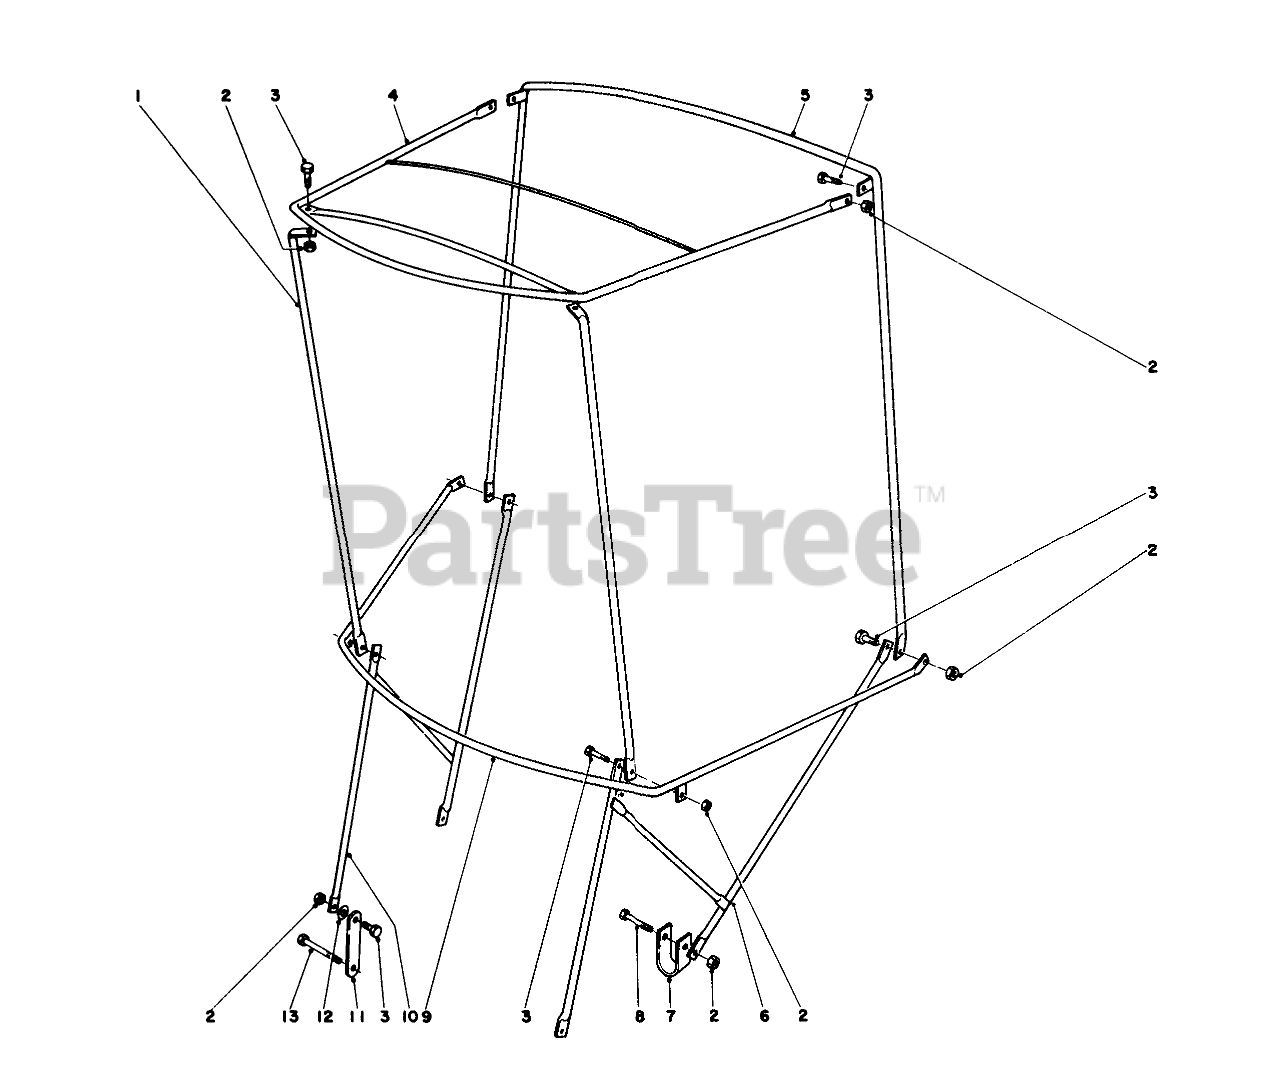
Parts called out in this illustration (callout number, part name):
2	NUT-LOCK
3	SCREW-HH
4	FRAME-TOP
5	BOW-VERTICAL, REAR
6	Attaching Bracket, L.H.
7	U CLAMP
8	SCREW-HH
9	BOW-CURVED
10	Attaching Bracket, R.H.
11	Mounting Strap
12	WASHER-LOCK/EXT
13	SCREW-HH
